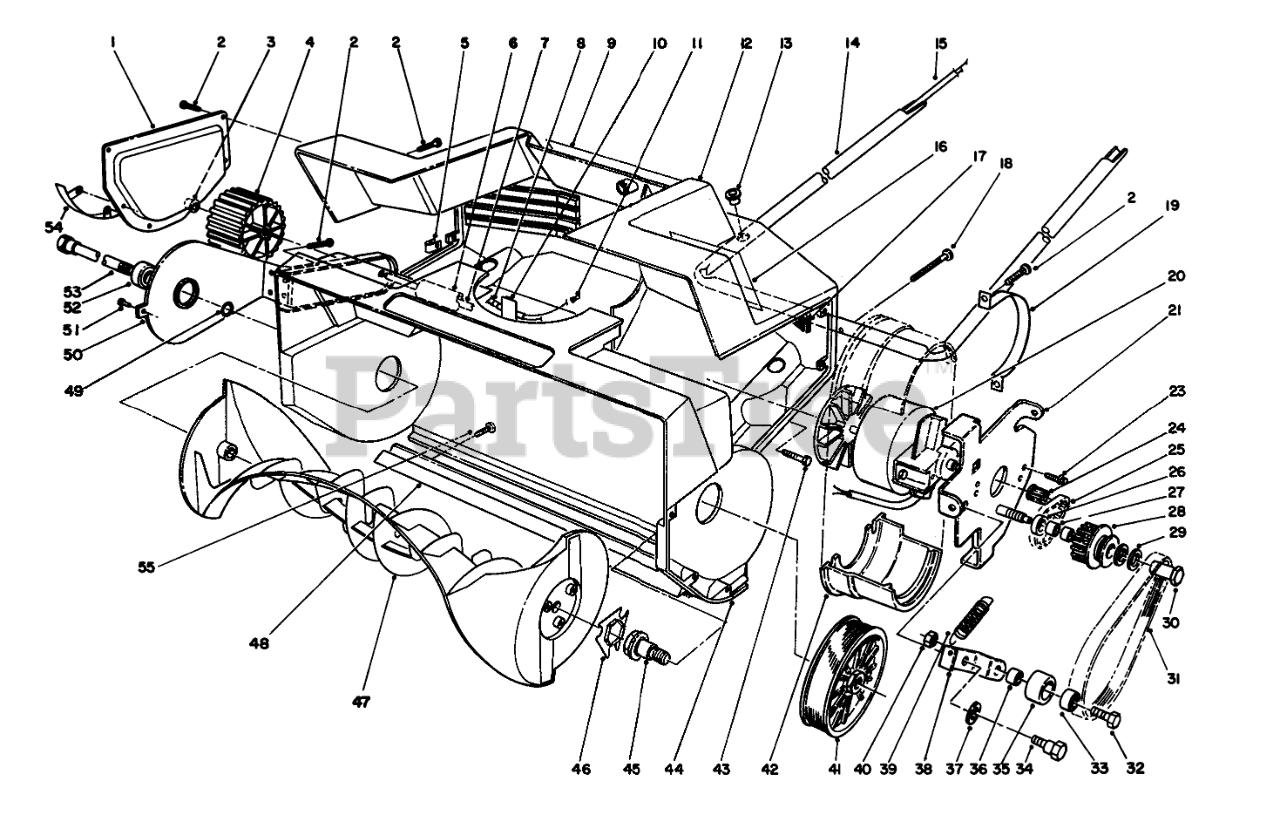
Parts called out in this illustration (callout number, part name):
1	PLATE - SIDE, PAINTED
2	Screw
3	PUSHNUT-CAP, WASHER
4	Wheel
5	U-CLIP
6	SLEEVE, AXLE
7	Shaft-Axle
8	Relief-Strain
9	Decal-Danger Used on Machines Serial Nos. (1000101 Thru 1111100)
10	CORD CLIP
11	Connector
12	Shroud-Housing
13	BUSHING
14	Tube-Lower Handle
15	Wire Harness
16	DECAL - WARNING
17	Filter-Foam
18	Screw-Pan Head
19	Strap-Motor
20	Motor
21	Motor Plate Assembly
23	Screw-Hex Washer Hd.
24	DRIVER PULLEY
25	BELT-PULLEY, IDLER/DRIVER
26	WASHER
27	Bearing
28	Pulley-Idler (Incl. Ref. #27)
29	WASHER-THRUST
30	Bolt-Idler
31	Belt-Drive
32	SCREW-HH
33	BEARING-BALL
34	SCREW-SHOULDER
35	Pulley
36	WASHER-IDLER
37	WASHER
38	Bracket-Idler
39	Spring
40	NUT-LOCK, NI
41	Pulley-Driven
42	Clamp-Motor Bracket
43	SCREW-HH
44	HOUSING, ROTOR, 1800
45	Shaft-Driver, Rotor
46	Coupler-Rotor
47	Rotor
48	Scraper
49	WASHER-THRUST
50	Bracket-Wheel (Incl. Ref. #52)
51	RIVET-POP
52	Bearing-Ball
53	Shaft-Rotor
54	Skid-Housing
55	Screw-Pan Head
